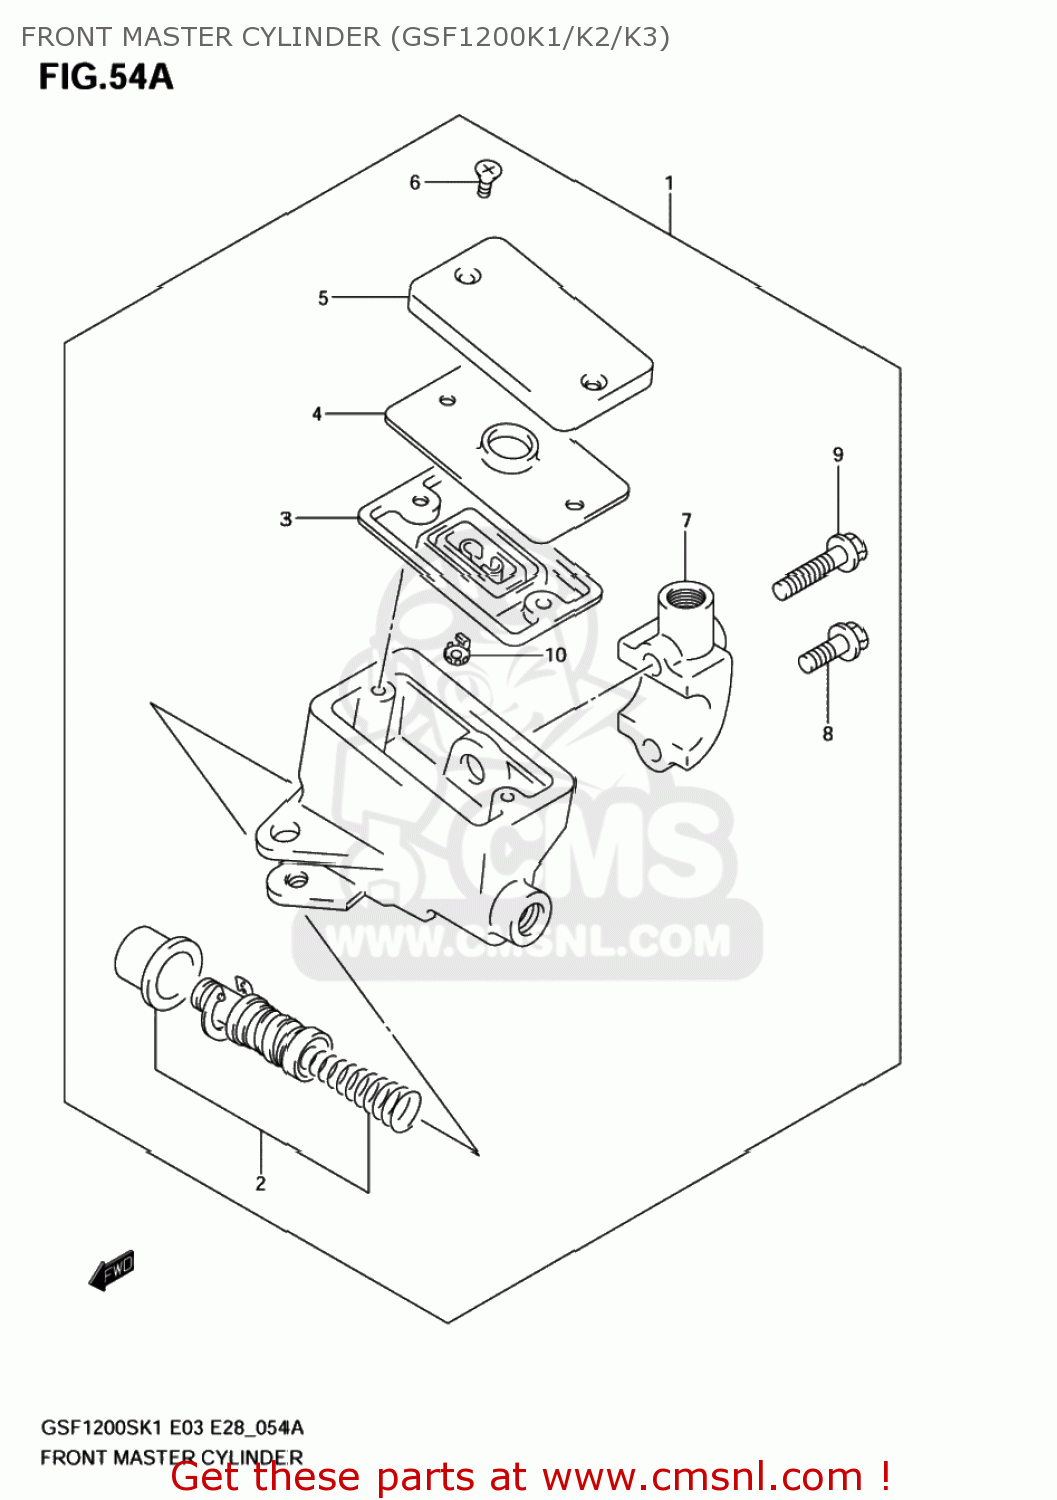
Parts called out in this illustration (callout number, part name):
1	CYLINDER ASSY,FR MASTER
2	PISTON & CUP SET
3	4
4	PLATE,DIAPHRAGM
5	CAP
6	SCREW
7	HOLDER
8	BOLT(6X25)
9	BOLT(6X38)
10	PROTECTOR
